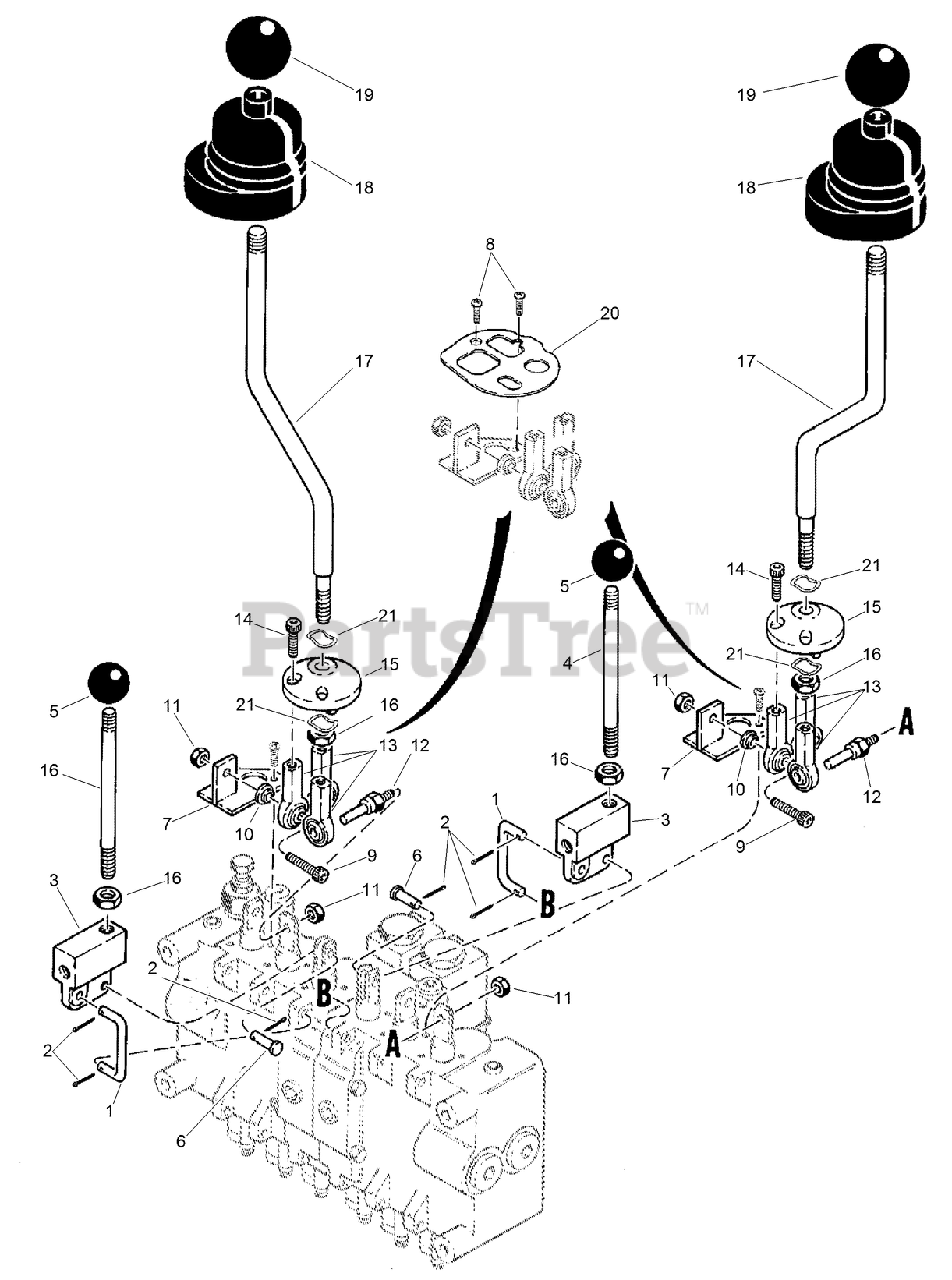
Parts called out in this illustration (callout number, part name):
2	PIN-Cotter 0.062 x 0.75 in ZN
6	PIN-CLEVIS
7	BRACKET
11	NUT-JAM
13	END-ROD
15	ADAPTER
16	NUT-Hex Jam 0.375-16 GR5 ZNd
